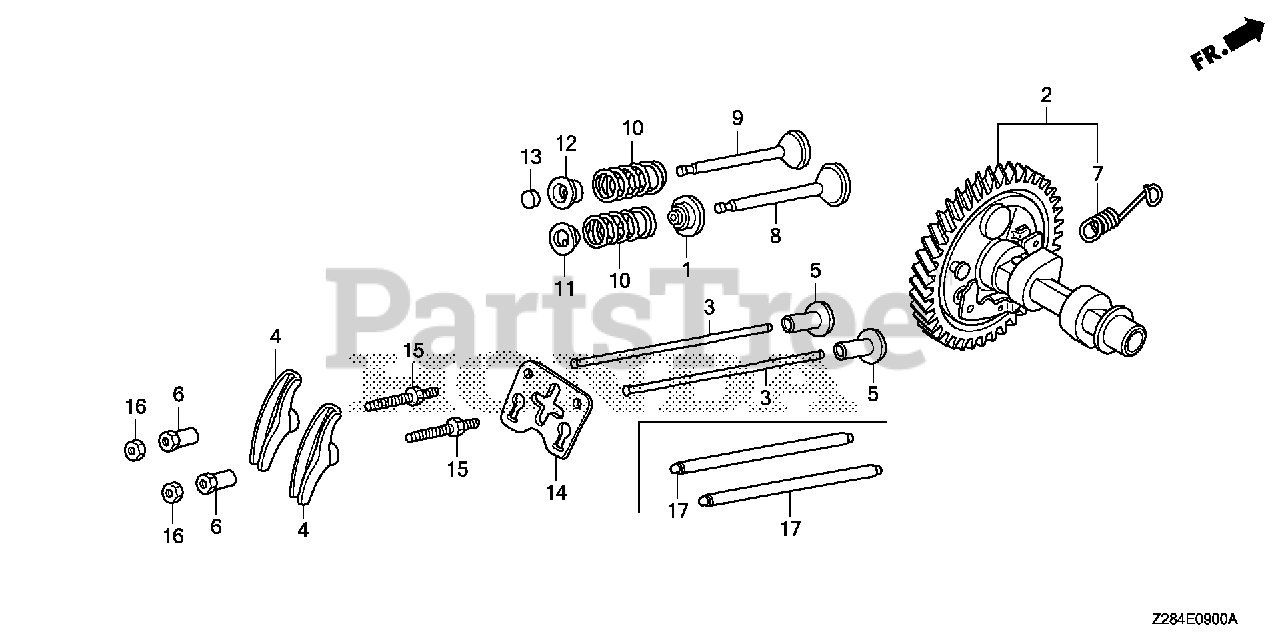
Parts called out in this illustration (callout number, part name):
1	SEAL, VALVE STEM
2	CAMSHAFT ASSY.
3	ROD, PUSH
4	ARM, VALVE ROCKER
5	LIFTER, VALVE
6	PIVOT, ROCKER ARM
7	SPRING, WEIGHT RETURN
8	VALVE, IN.
9	VALVE, EX.
10	SPRING, VALVE
11	RETAINER, IN. VALVE SPRING
11	RETAINER, VALVE SPRING (EXHAUST SIDE)
12	RETAINER, EX. VALVE SPRING
13	ROTATOR, VALVE
14	PLATE, PUSH ROD GUIDE
15	BOLT, PIVOT (8MM)
16	NUT, PIVOT ADJ.
